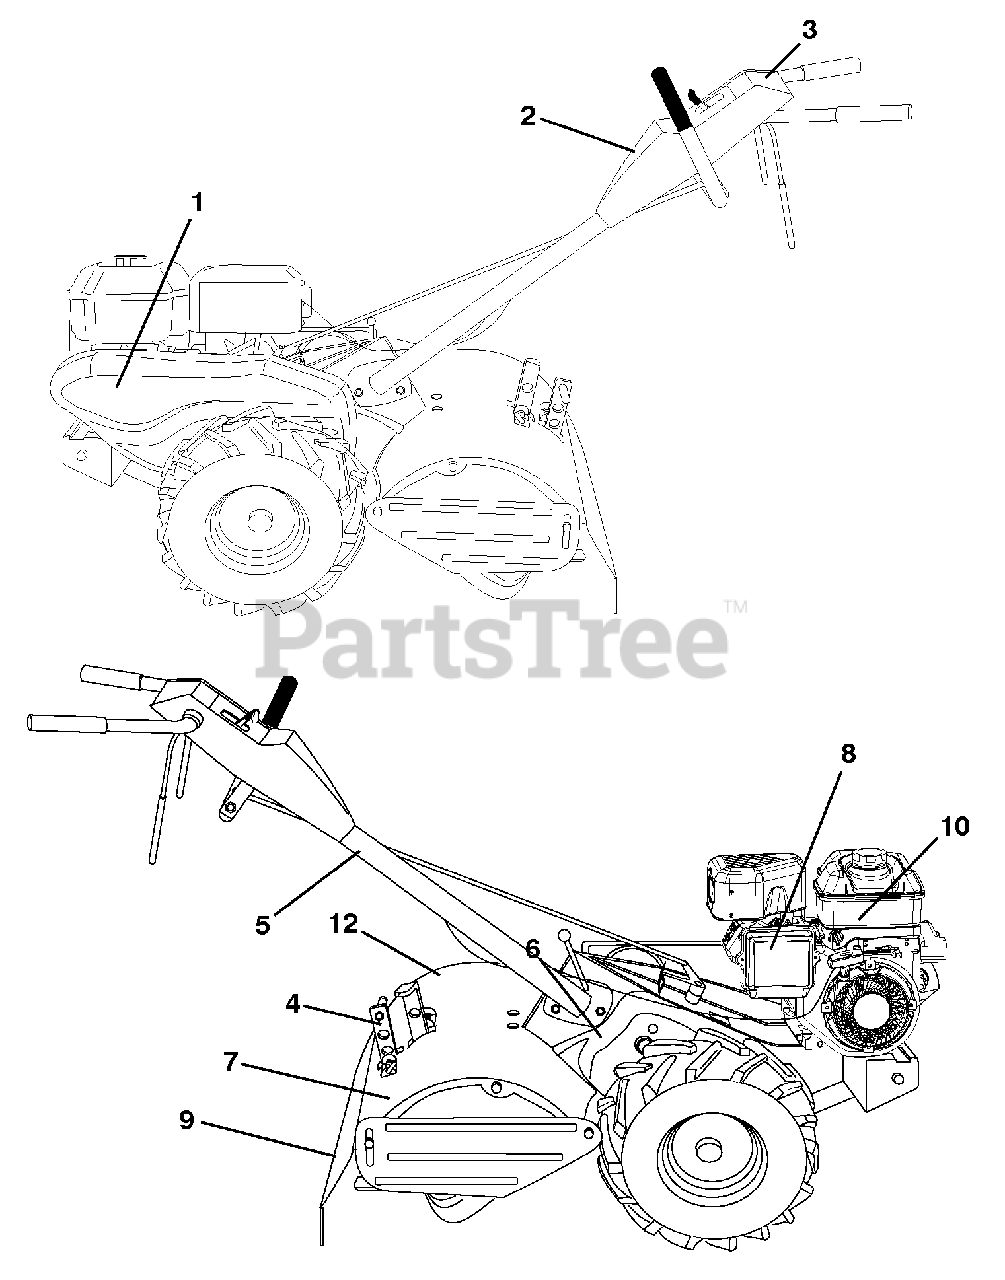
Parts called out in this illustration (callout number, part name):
1	Decal, Belt, Guard, Badge
2	Decal, Console
3	Decal, Console
4	Decal, Tine Shield
5	Decal, Hand Placement
6	Decal, Shift Indicator
7	Decal, Reverse
8	Decal, Engine B&S
9	Decal, Warning, Rotating Tines
10	Decal, Engine Intek REF
12	Decal, Forward
